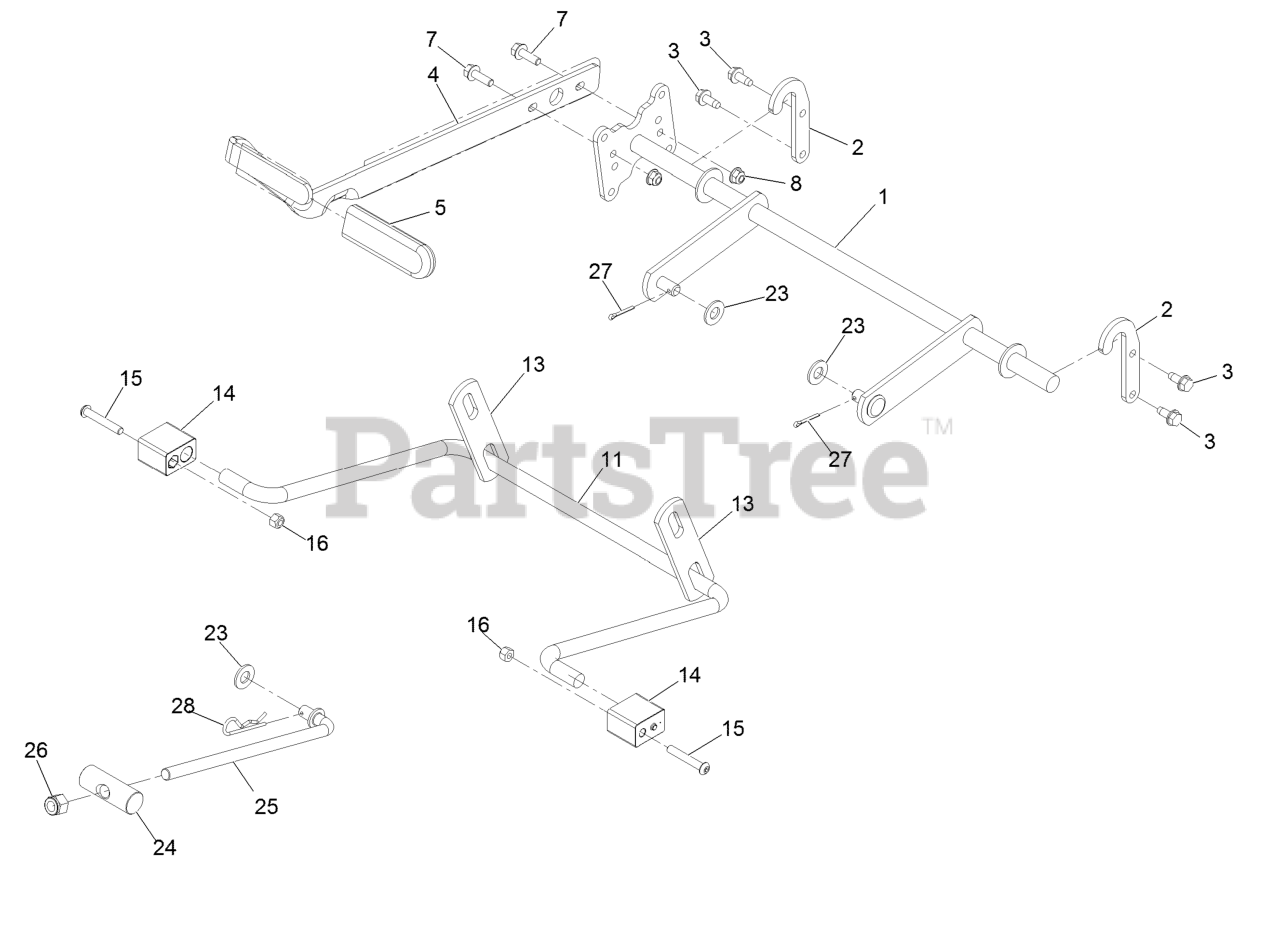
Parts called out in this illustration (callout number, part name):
1	Lift-Deck, Narrow
2	Bracket-Lift
3	Screw-HWH 5/16-18 X 3/4 Tf
4	Handle-Deck Lift
5	Grip-Lever
7	Screw-HH Flg 5/16-18 X 1
8	Nut-Nyloc 5/16-18 Flg
11	Arm-Lift, Rear
13	Link-Lift
14	Block-Pivot
15	Screw-Button Head 5/16-18 X 2.00
16	Nut-Nyloc 5/16-18
23	Washer-1/2 SAE
24	Pin-Pivot
25	Rod-Mount, Deck
26	Nut-Nyloc 1/2-20
27	Pin-Cotter 1/8 X 1
28	Hairpin-Cotter
